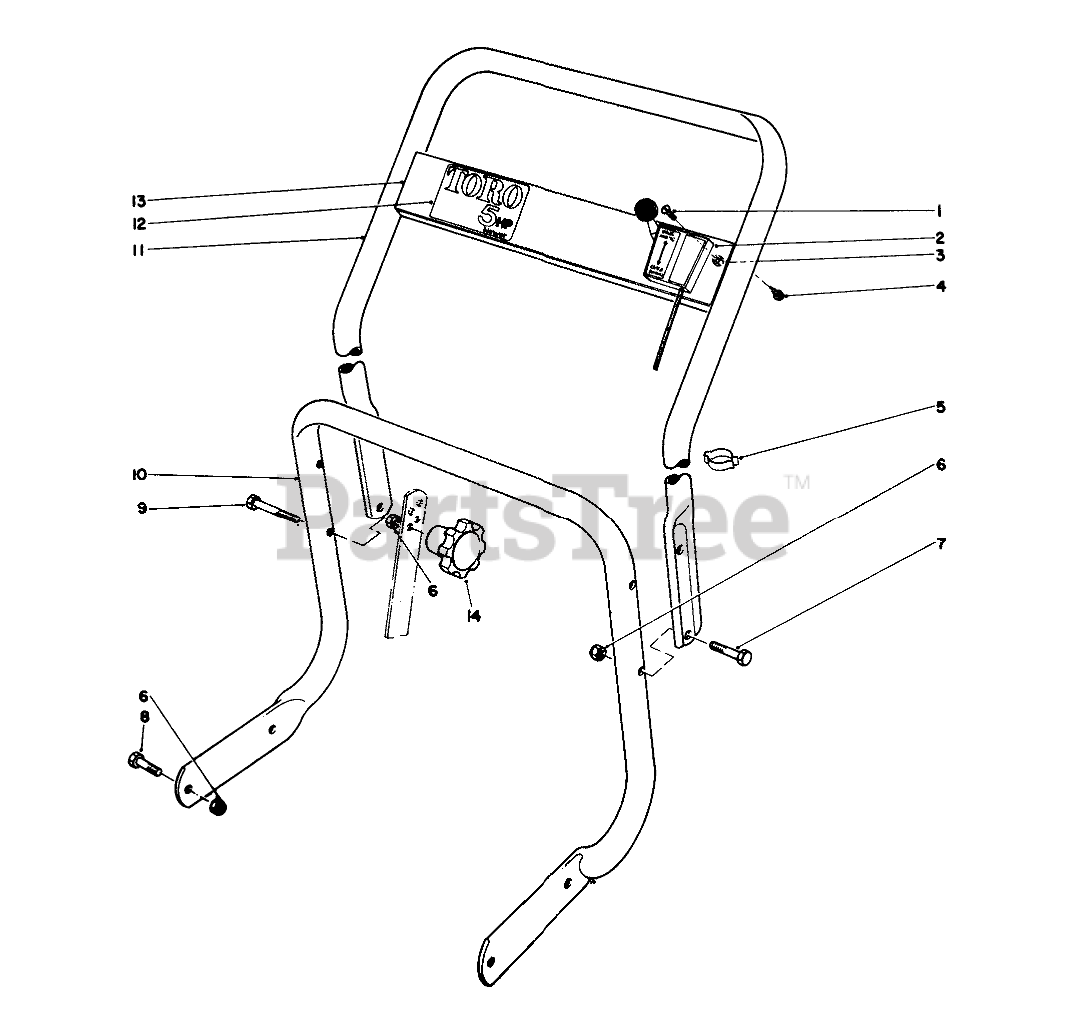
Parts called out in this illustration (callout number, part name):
1	8-32 X 1/2 RND HD MS
2	Throttle Control
3	NUT-HEX
4	SCREW-HWHTF
5	BODEN CLIP
6	NUT-LOCK, CONE
7	SCREW-HH
8	SCREW-HH
9	SCREW-HH
10	HANDLE
11	UPPER HANDLE
12	ESCUT PLATE DECAL
13	BLOWER ESCUTCHEON PLT
